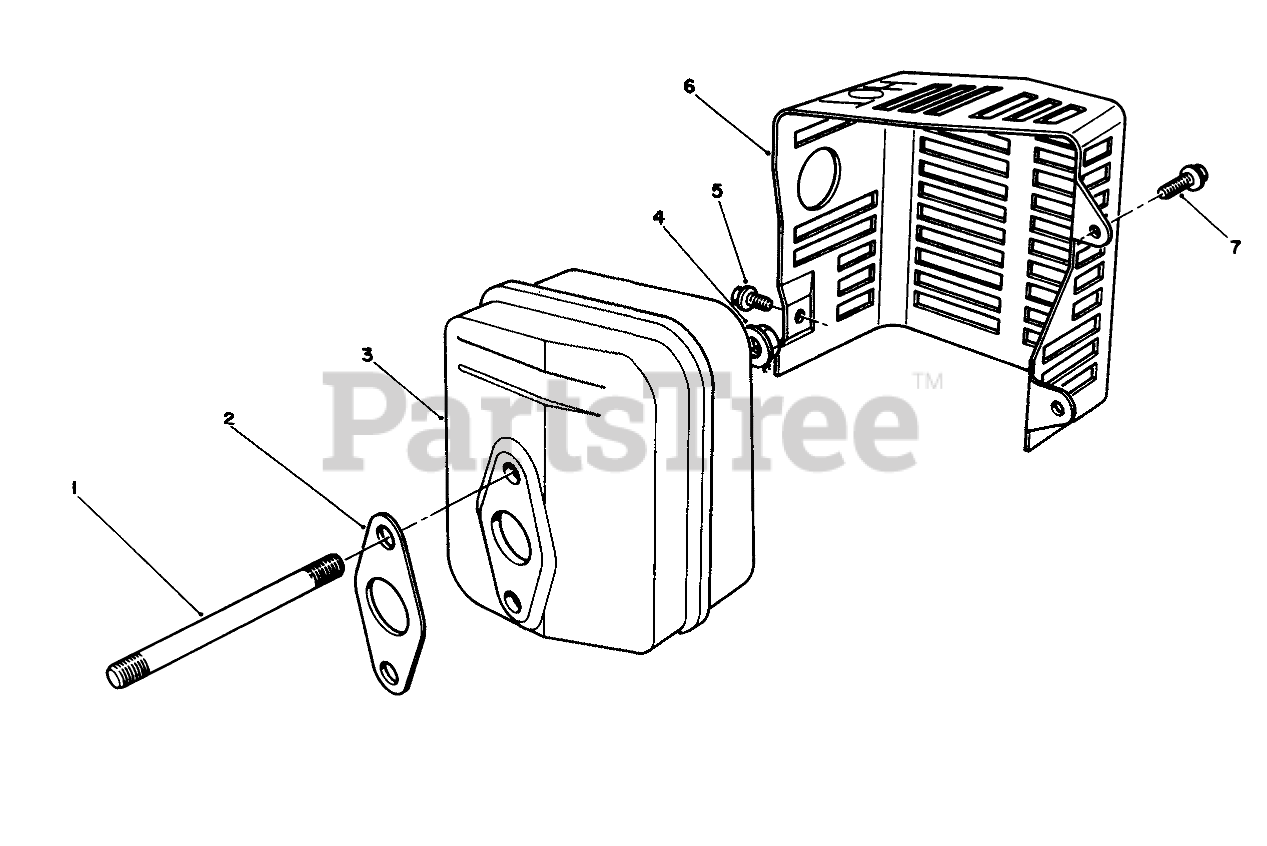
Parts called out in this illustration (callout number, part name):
2	GASKET
3	MUFFLER
5	SCREW
6	COVER
